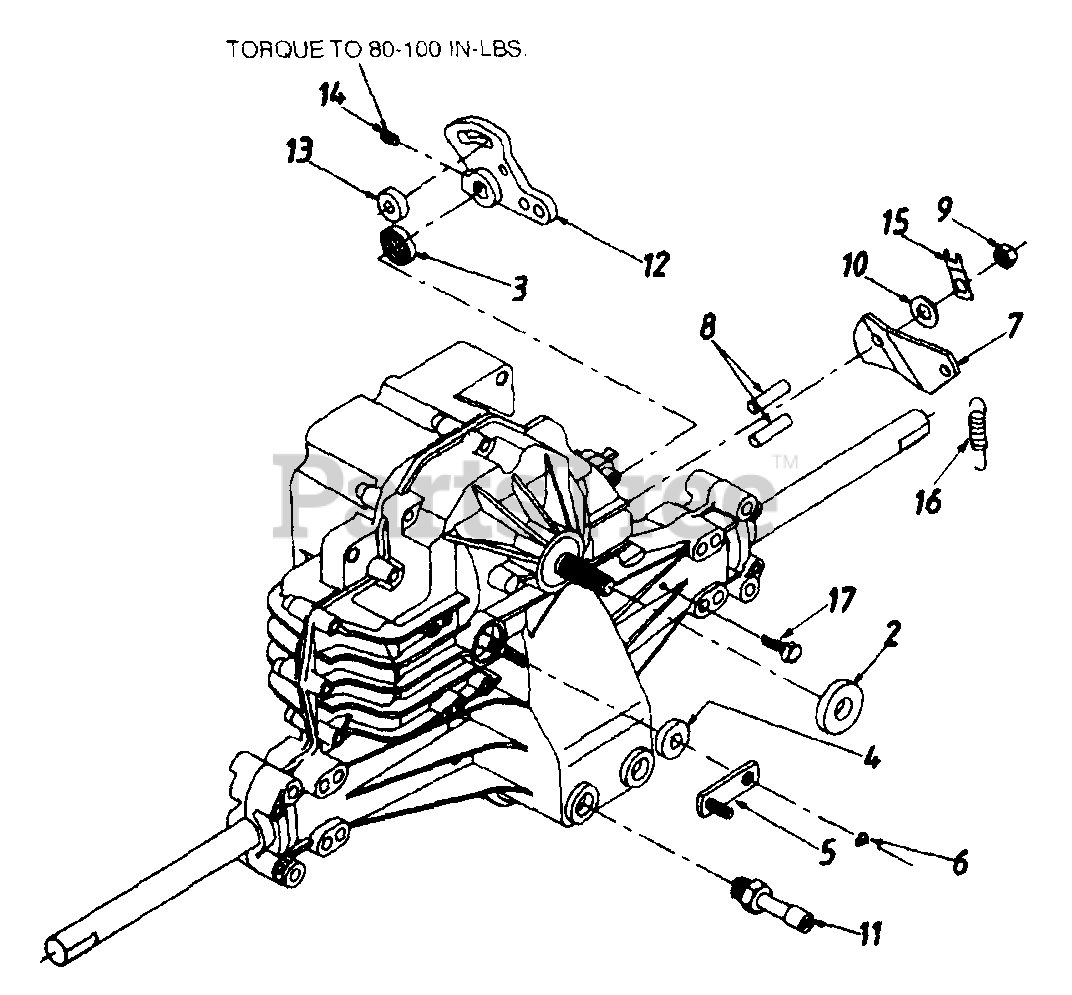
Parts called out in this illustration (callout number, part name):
4	Seal-Lip 10x 25X7
5	Arm Bypass
6	Ring-Retaining
7	Arm-Actuating
8	Pin-Actuating
9	Nut-Hex Lock 5/16-24
10	Washer 7/16" x 7/8" x .06"
11	Breather Ass'y.
12	Arm-Control
13	Puck-Dampener
14	Set Screw
15	Strap, Locking
16	Ext. Spring
17	Self Tapping Scr. #10-32
